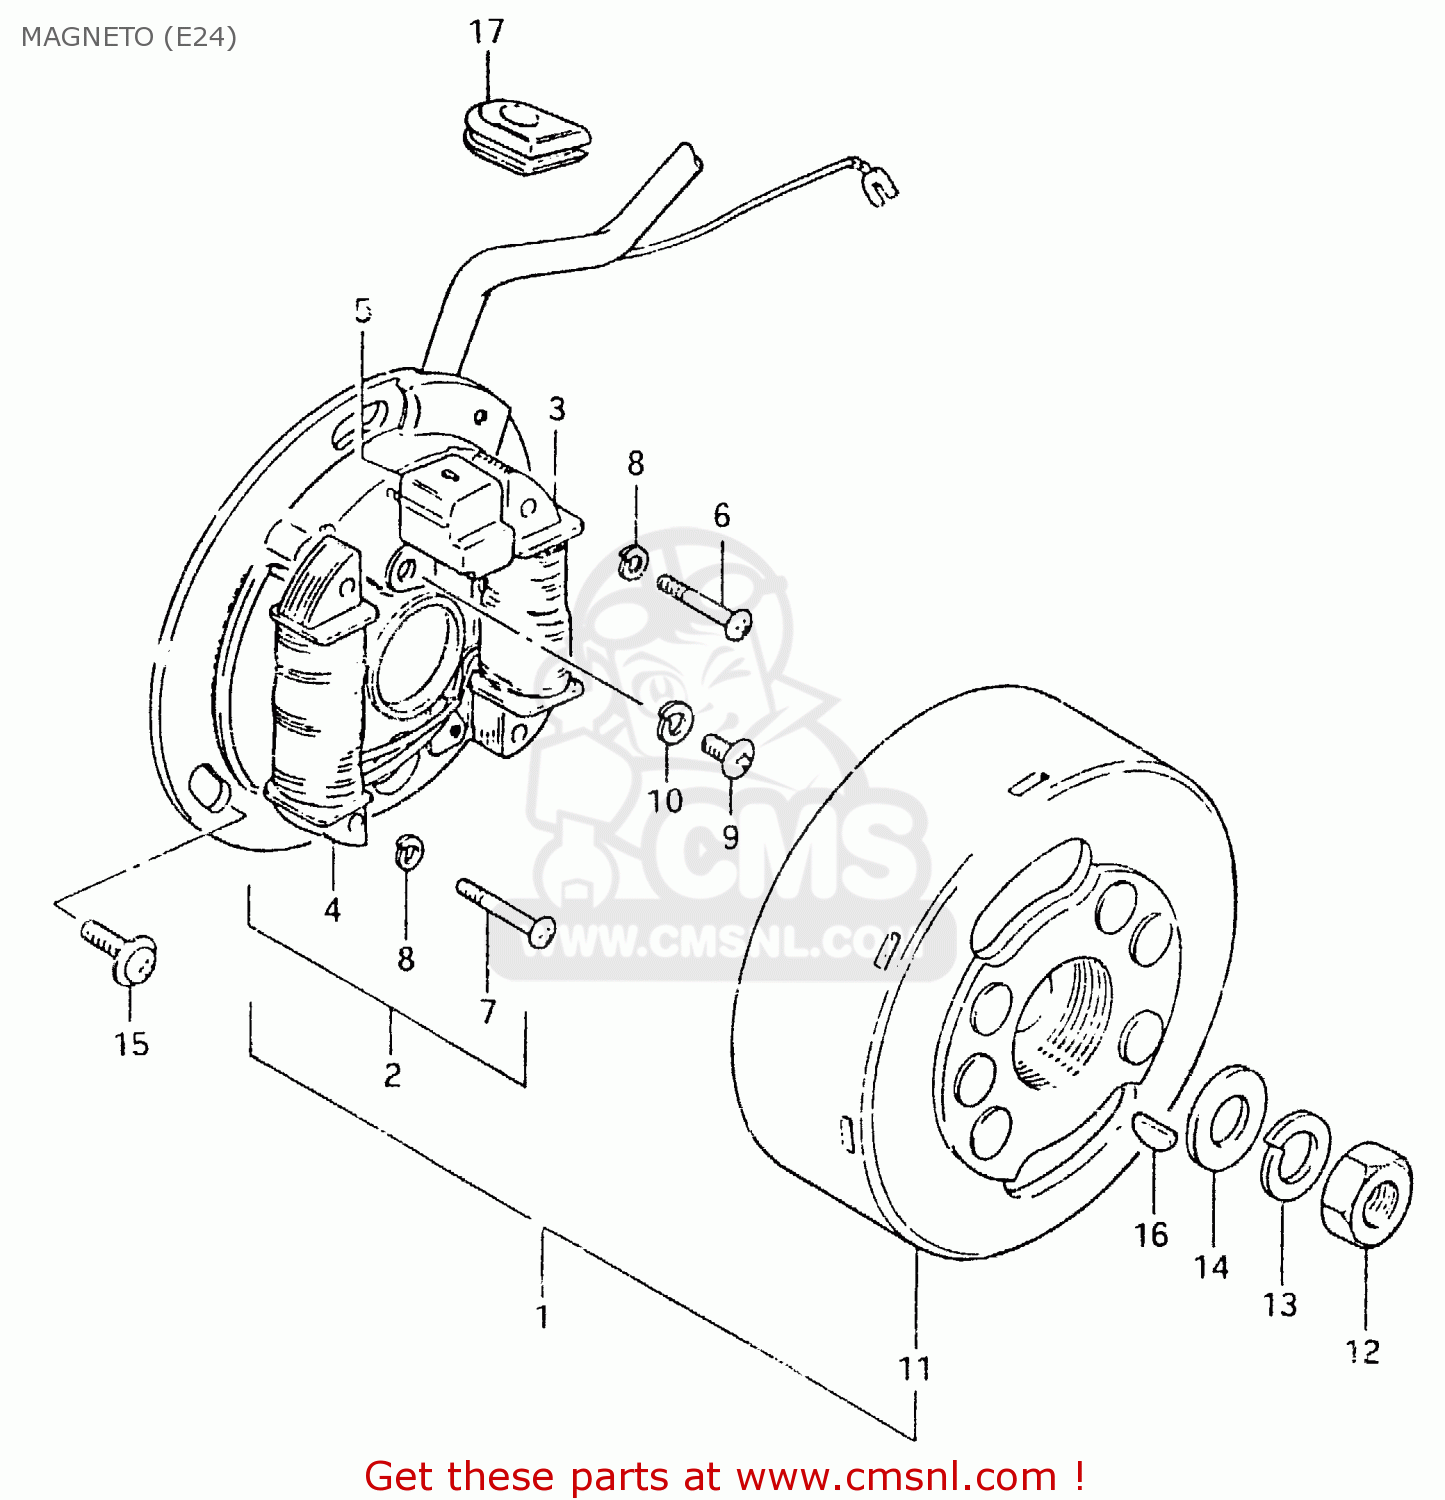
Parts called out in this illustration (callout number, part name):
1	MAGNETO ASSY
2	STATOR ASSY
3	COIL, LIGHTING
4	COIL
5	COIL,PULSER
6	SCREW 4X25
7	SCREW
8	LOCK WASHER
9	SCREW
10	LOCK WASHER
11	ROTOR
12	NUT (10MM)
13	LOCK WASHER
14	WASHER
15	SCREW(5X14)
16	KEY
17	GROMMET
